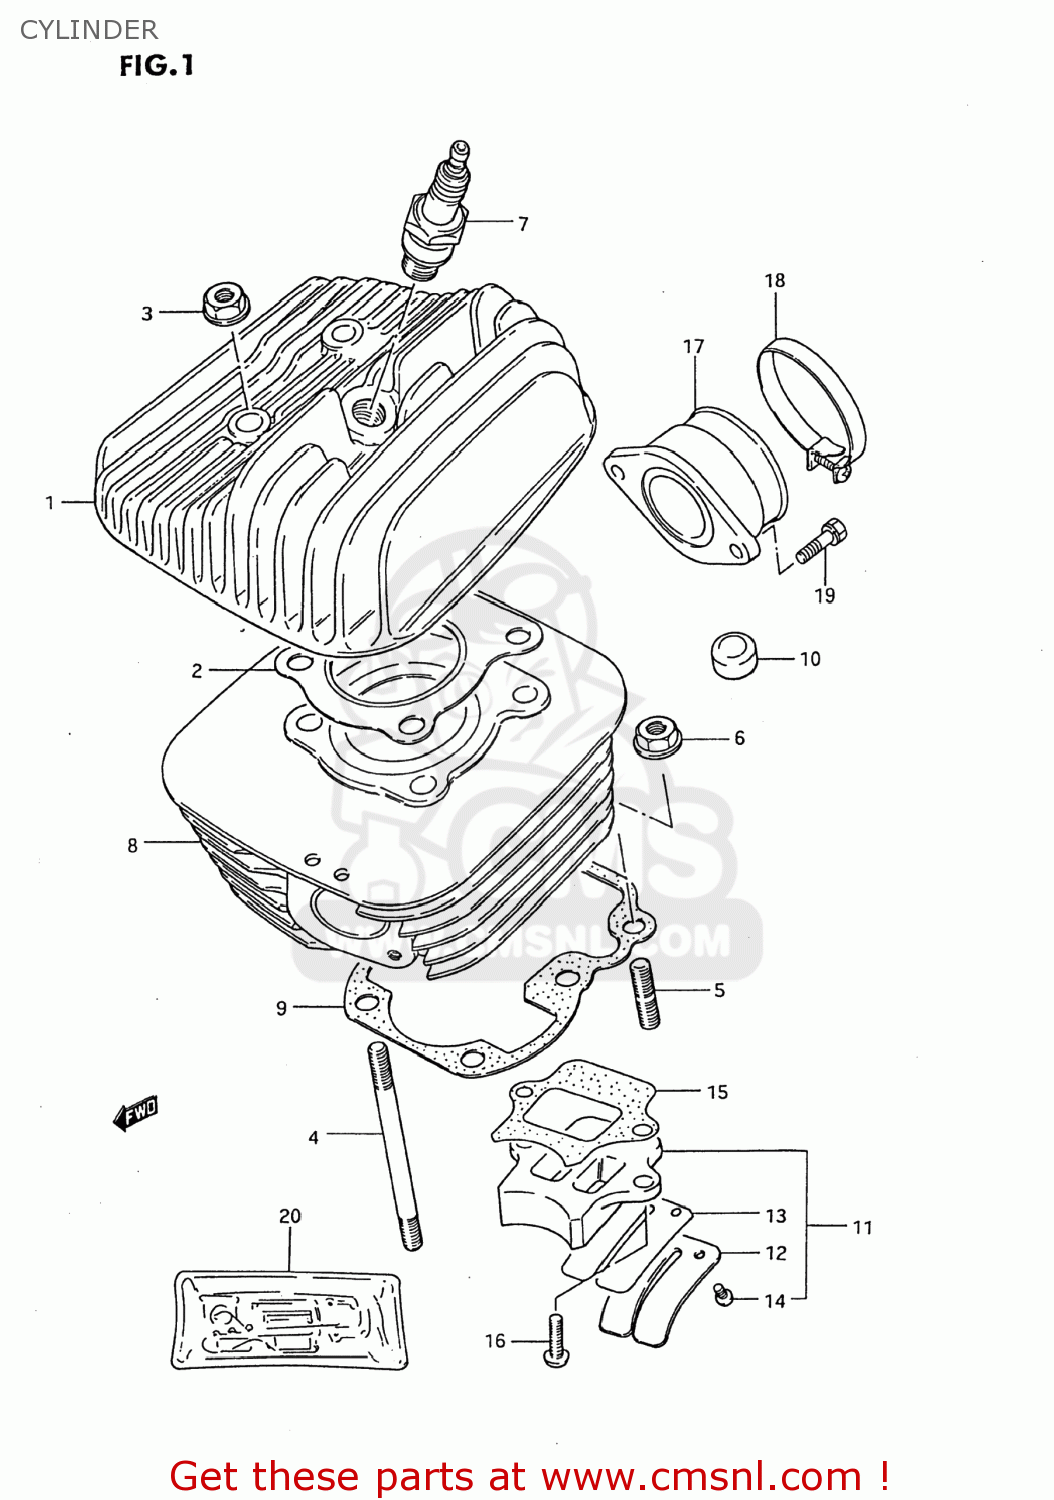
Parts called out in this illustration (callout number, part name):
1	HEAD,CYLINDER
2	GASKET,CYLINDER HEAD (NAS)
3	NUT
4	BOLT,STUD
5	STUD 6X20
6	NUT
7	SPARK PLUG B7ES
8	CYLINDER
9	GASKET,CYLINDER (NAS)
10	PAD,CYLINDER
11	VALVE ASSY,REED
12	STOPPER,REED VALVE
13	VALVE,REED
14	SCREW
15	GASKET,REED VALVE (MCA)
16	SCREW
17	PIPE,INTAKE
18	CLAMP
19	BOLT
20	GASKET SET (NAS)
